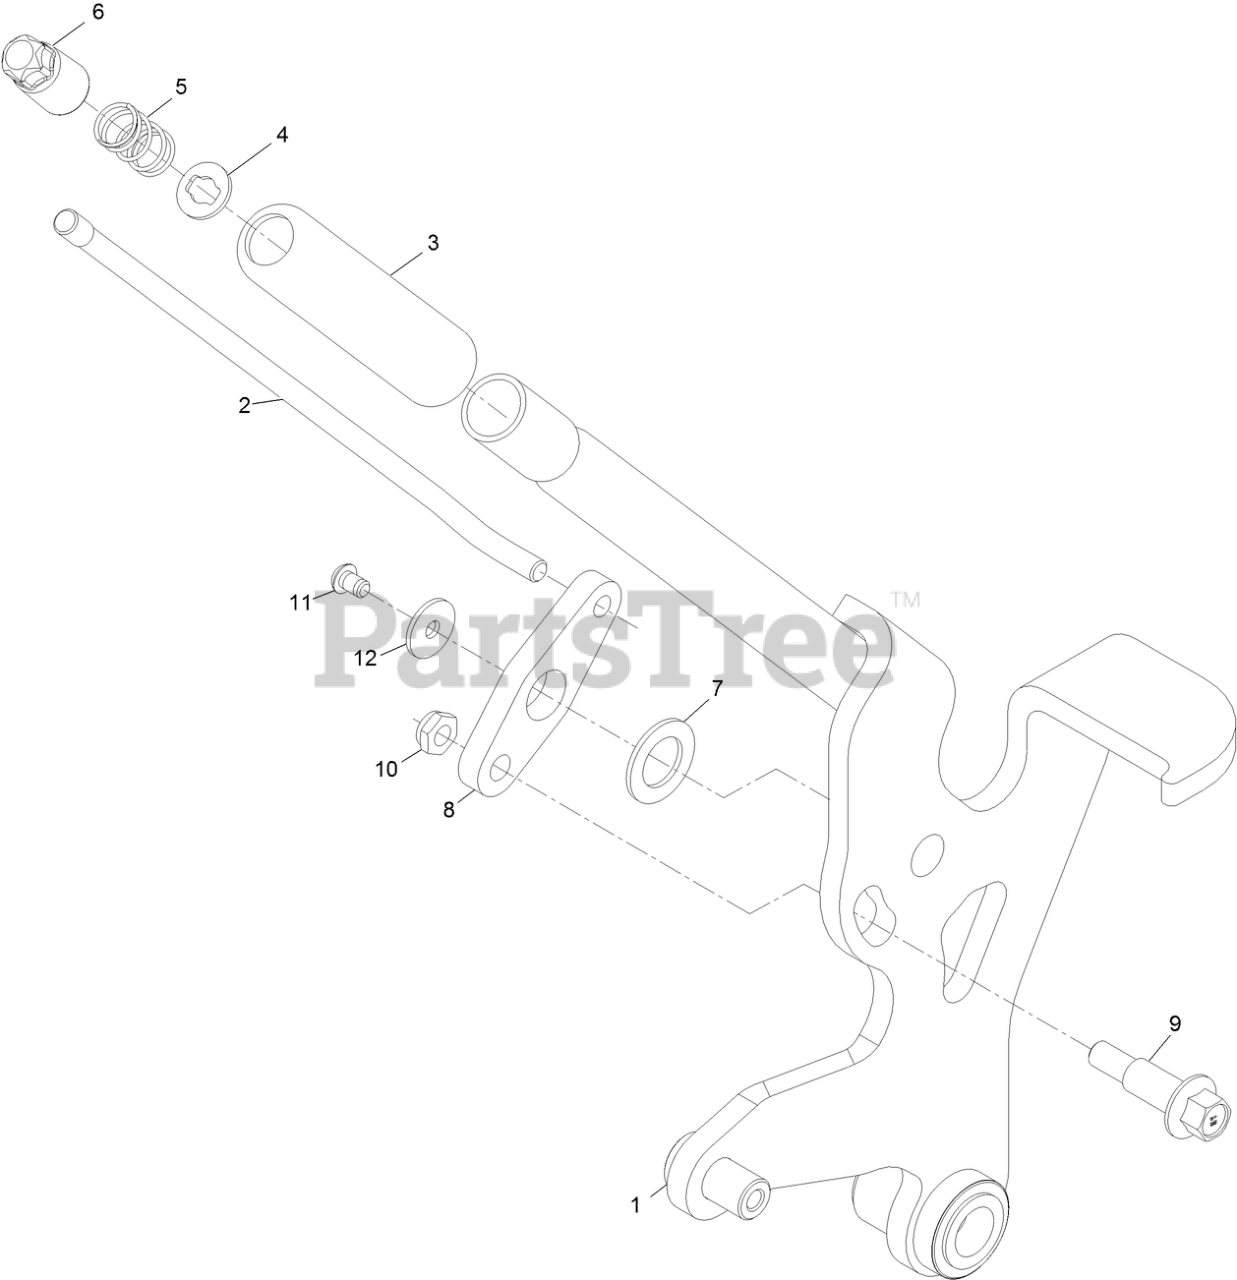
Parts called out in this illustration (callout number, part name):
1	ASM, LEVER W/ BUSHINGS
2	LINKAGE, HOC LEVER
4	WASHER-SPECIAL
5	SPRING-COMPRESSION
6	BUTTON, PUSH
7	WASHER-NYLON
8	ARM, TRANSPORT
9	SCREW-BH
11	SCREW-BHT
12	WASHER
